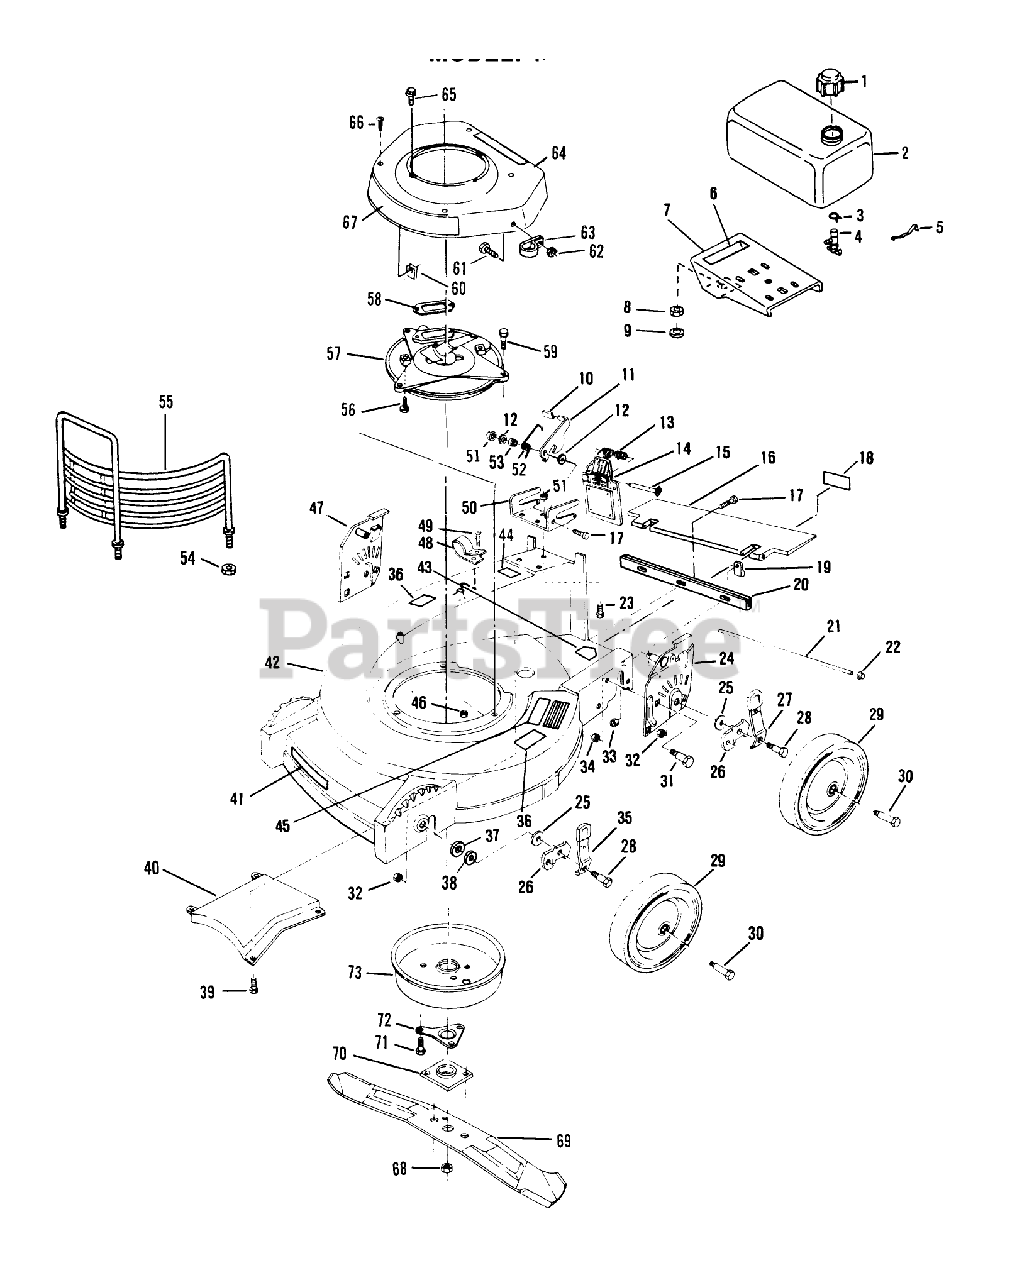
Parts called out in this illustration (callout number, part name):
1	FUEL CAP & INSERT
3	CLAMP - HOSE S
4	VALVE&SCREEN SM
5	SPRING
7	BRACKET - TANK
8	LOCKNUT E
9	WASHER
10	KNOB (S&R)
13	SPRING ASOC
15	ROD (RB&W)
16	T/SHIELD SM&P
23	SCREW
25	WASHER
28	BOLT
29	WHL & TIRE AY
30	BOLT-SHOULDER
32	LOCKNUT
33	LOCKNUT E
34	NUT-LOCK F
35	SPRING ARM ASM
37	WASHER
38	WASHER
40	BAFFLE CHUTE PL
46	NUT-LOCK F
49	SCREW LAWRENCE
51	LOCKNUT E
52	SPRING
54	NUT-LOCK F
56	SCREW V
57	M/PLATE
59	SCREW-HH
60	PUSHNUT F
62	LOCKNUT E
65	SCREW SEMS SM
66	SCREW - SELF TAPPING
68	NUT-BLADE
70	PLATE AND COLLAR ASM
71	SCREW
72	SUPPORT F
73	MUFFLER COVER F
